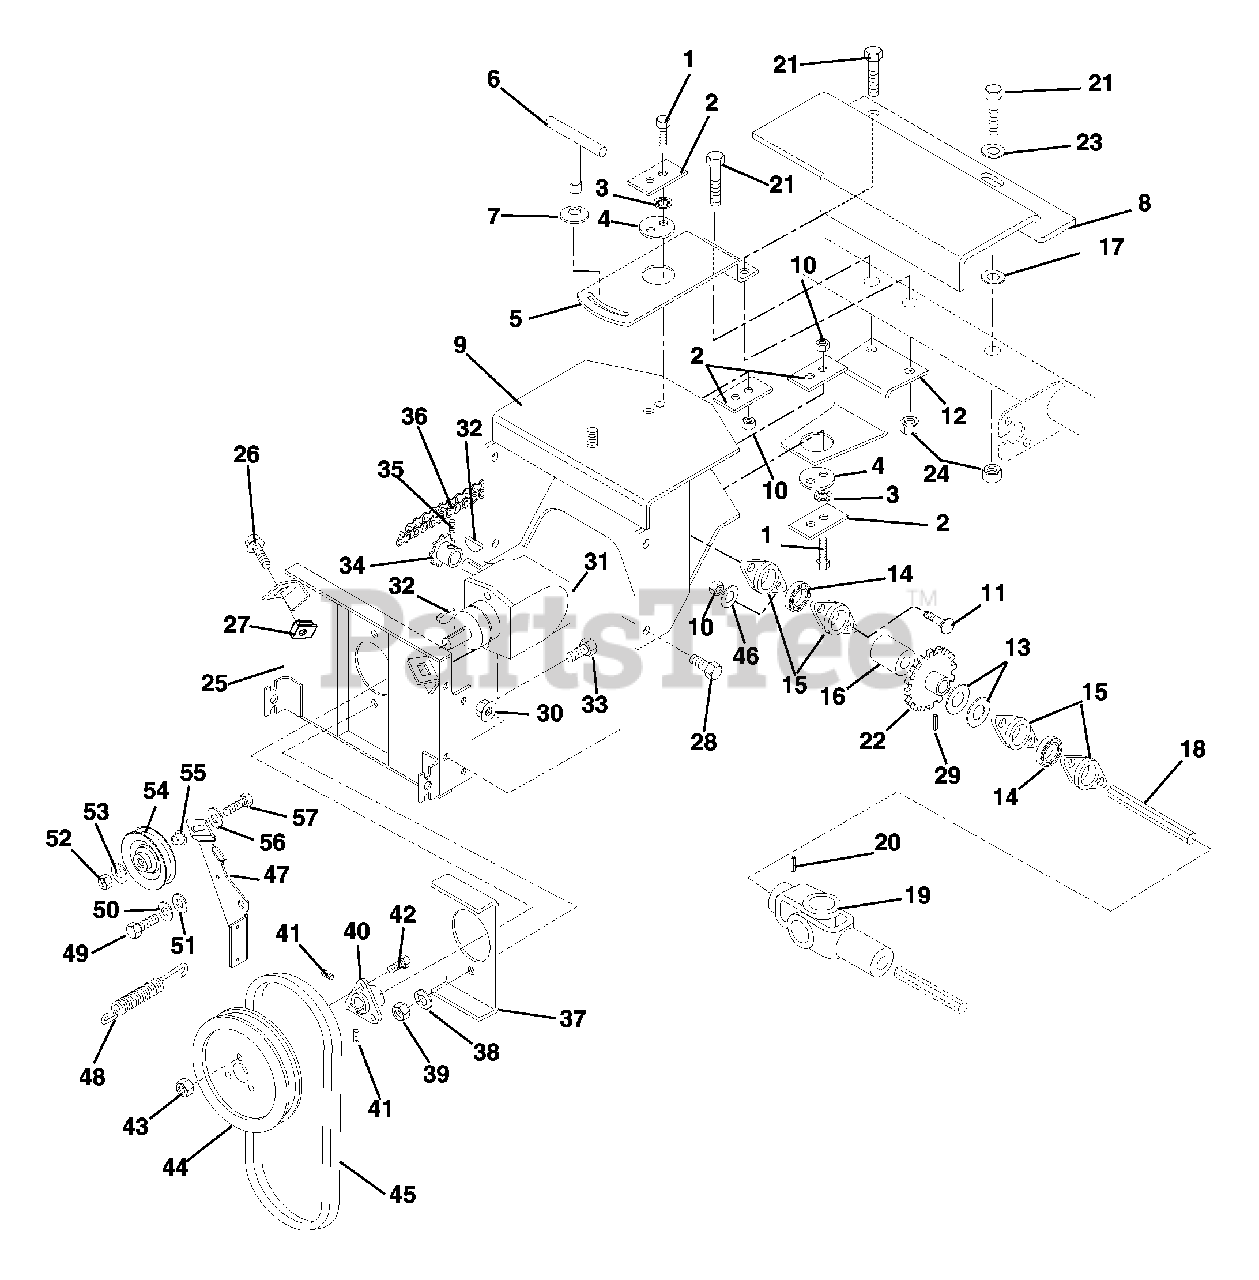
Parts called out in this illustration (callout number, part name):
1	Bolt, Hex .31-18 x 1.25 Grade 5
2	Retainer
3	Washer, Locking Internal .313 x .030
4	Pivot, Center
5	Plate, Top Mount
6	T-Lock Handle
7	Washer, Cupped Serrated .38
8	Guard, Shaft
9	Frame, Adapter
10	Nut, Locking Top .31-18
11	Bolt, Round Head Square Neck .31-18 x .75 Grade 5
12	Plate, Bottom Mount
13	Washer, Flat Steel 1.015 x 1.500 x .125
14	Bearing, Ball
15	Flange, Bearing
16	Spacer 1.006 x 1.307 x .500
17	Washer, Flat Steel .390 x .88 x .18
19	Universal Joint
20	Pin, Roll .188 x 1.50
21	Bolt, Hex .38-16 x 3.25 Grade 5
22	Sprocket
23	Washer, Flat Steel .406 x .812 x .065
24	Nut, Locking Center .38-16
25	Plate, Mounting Broom
26	Bolt, Hex Flanged Whizloc Head .38-16 x .75
27	Nut, Retainer .38-16
28	Bolt, Hex .38-16 x .75 Grade 5
29	Pin, Roll .188 x 1.75
30	Nut, Locking Center .38-16
31	Gear Box Assembly
32	Key, Woodruff .188 x .75 x .313 SAE 9
33	Bolt, Hex .38-16 x 1.25 Grade 5
34	Sprocket
35	Screw, Set .25-20 x .25 Socket Head Cup Point
36	Chain
37	Plate, Stiffener
38	Washer, Lock .38 x .094
39	Nut, Hex .38-16
40	Hub Assembly
41	Screw, Set .31-18 x .38 Socket Head Cup Point
42	Bolt, Serrated Round Head Slotted .31-18 x .75
43	Nut, Locking Flanged .31-18
44	Pulley-V 9.00 x 1.25
45	V-Belt 4L 37.30
46	Washer, Flat Steel .38 x .875 x .083
47	Arm, Auger/Brake-High with Lining
48	Spring, Tension .062 x .56 x 8.00
49	Bolt, Hex .31-18 x .75 Grade 5
50	Washer, Locking .312 x .097 Heavy
51	Washer, Flat Steel .328 x 1.00 x .094
52	Nut, Locking Center .31-18
53	Washer, Flat Steel .344 x .688 x .065
54	Idler
55	Spacer, Bearing
56	Washer, Flat Steel .38 x .875 x .083
57	Bolt, Hex .31-18 x 1.25 Grade 5
